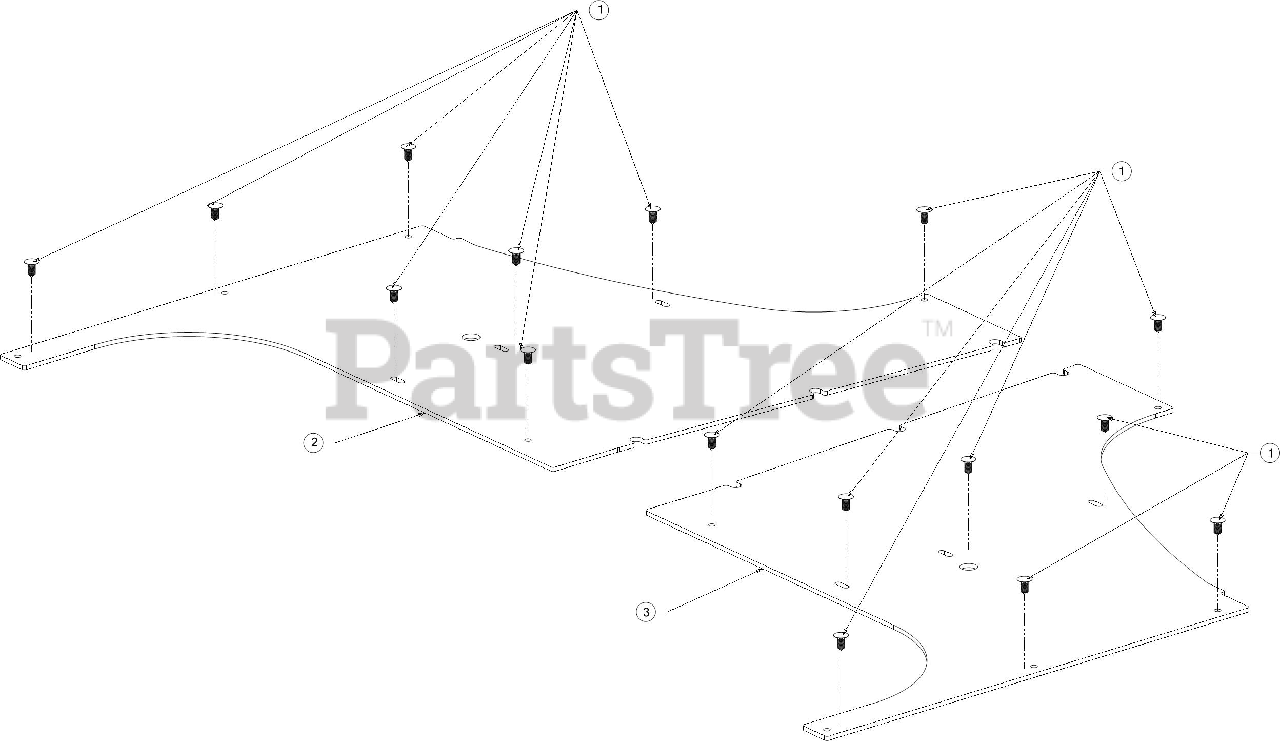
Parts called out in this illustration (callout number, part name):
1	RETAINER PAN CLIP
2	FLOOR MAT:4X4 (LH)
3	FLOOR MAT:4X4 (RH)
